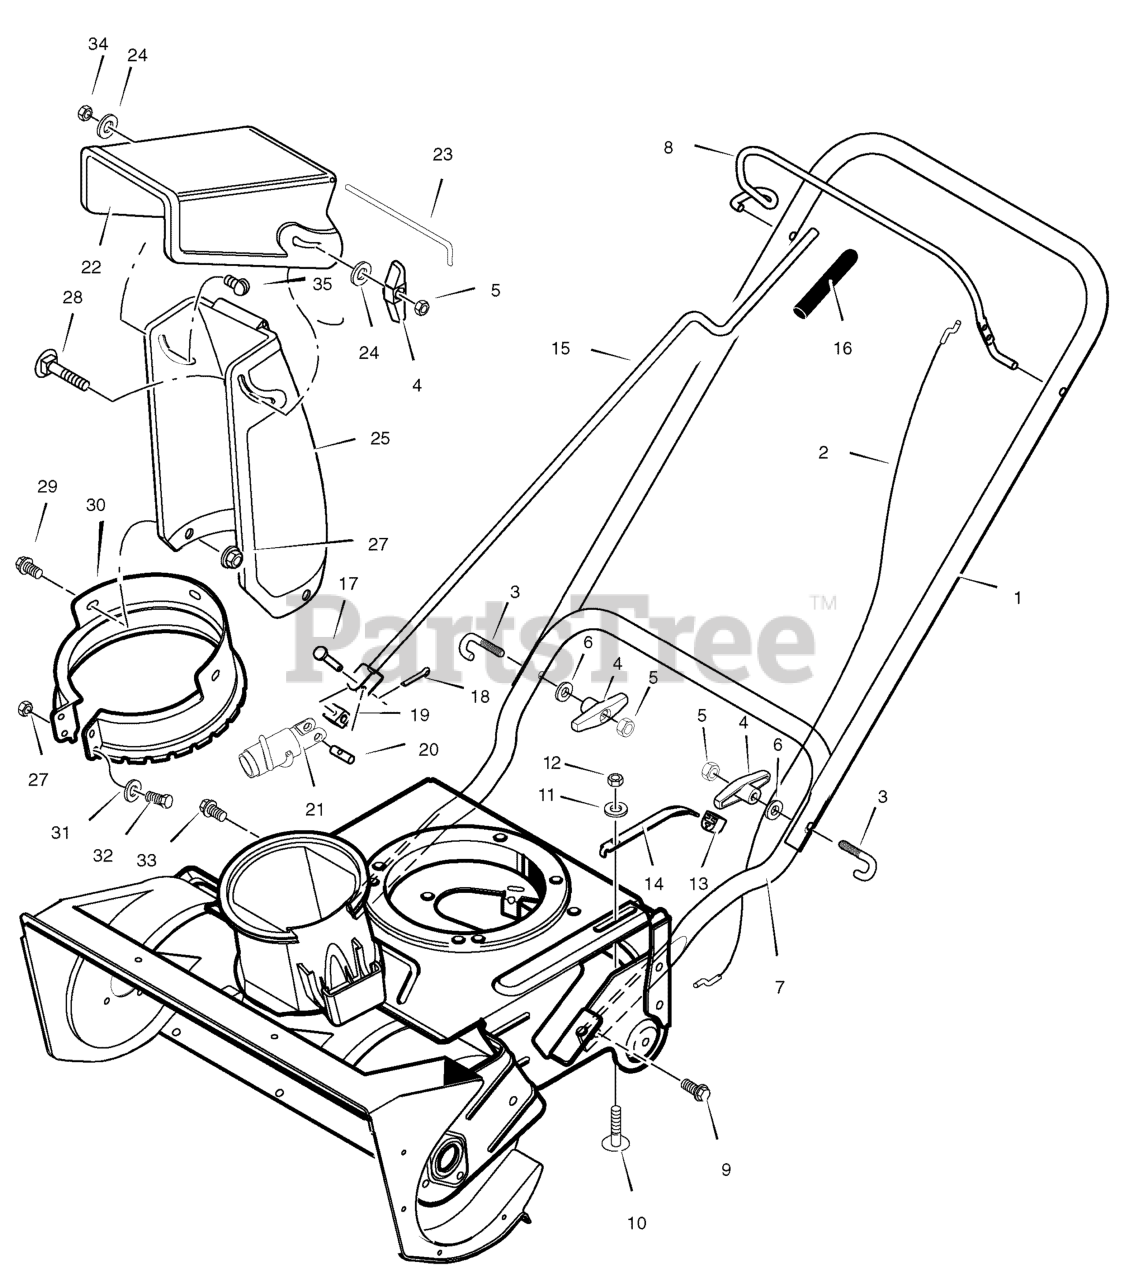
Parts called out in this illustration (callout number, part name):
1	Handle, Upper
2	Cable, Auger Drive
5	Nut
7	Handle, Lower
8	Lever, Auger Drive
9	Screw, 5/16-18 x 0.75
13	Bushing, Tensioner
14	Bracket, Cable Tensioner
15	Rod, Crank
16	Grip, Crank Rod
17	Pin, Clevis
18	Pin, Cotter
19	Block, Universal Pivot
21	Gear, Worm
22	Deflector
23	Pin, Pivot
24	Washer
25	Chute, Discharge
30	Ring, Chute
31	Washer
33	Screw, 5/16-18 x 0.75
34	Locknut
